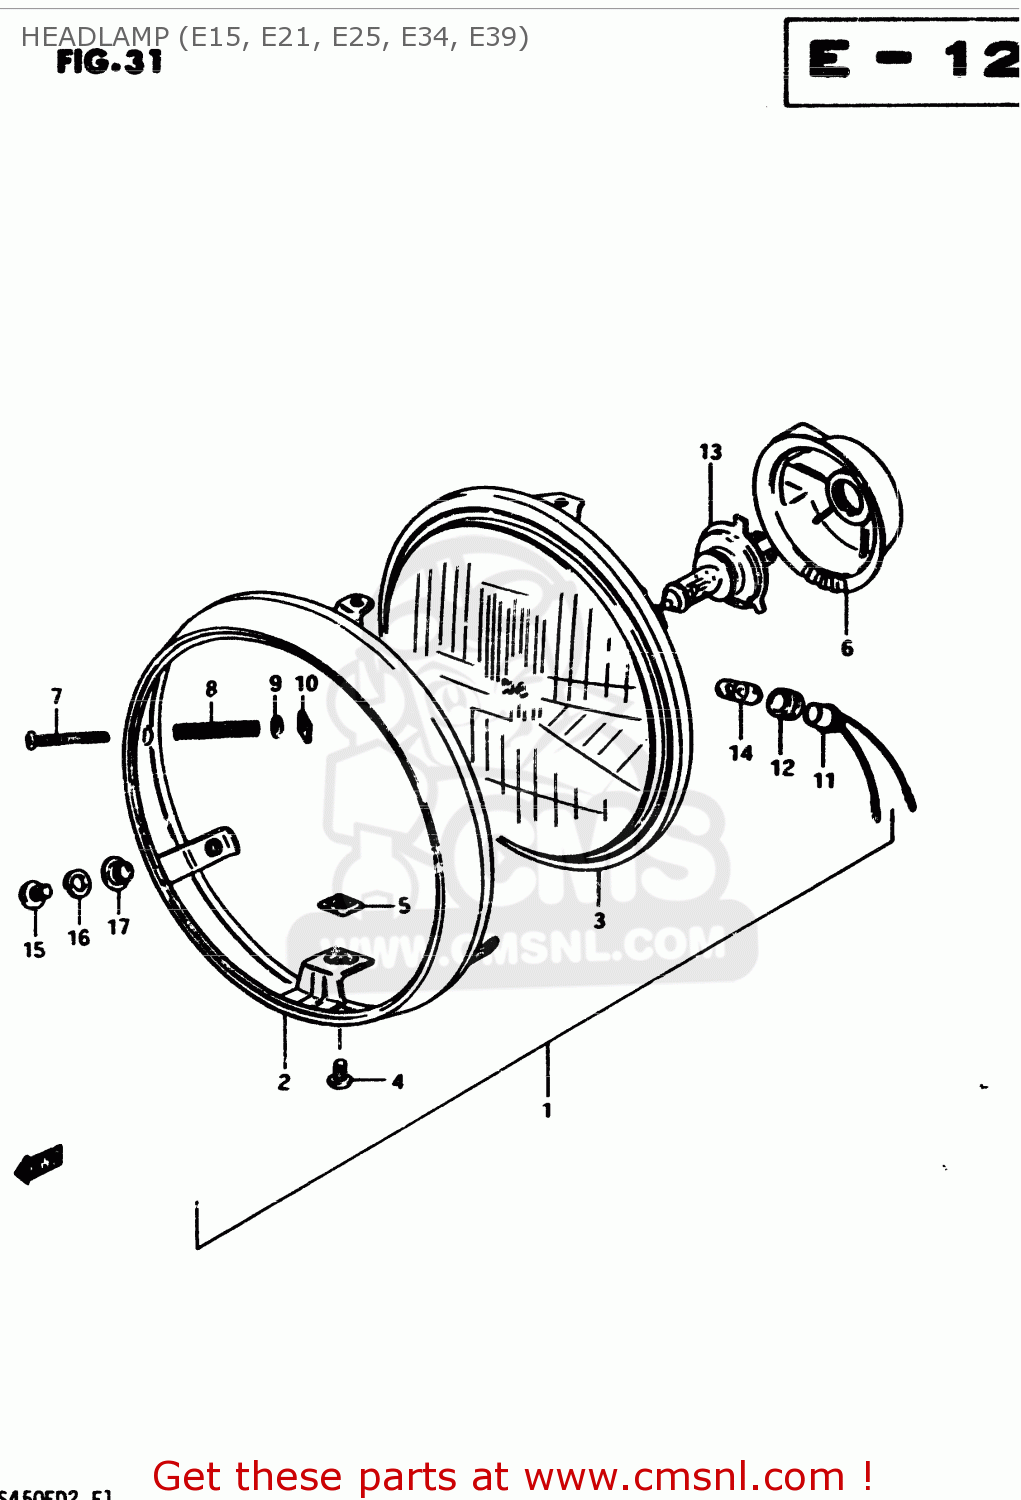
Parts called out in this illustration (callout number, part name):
1	HEADLAMP ASSY
2	RIM
3	LAMP UNIT
4	SCREW
5	NUT,ADJUSTING
6	COVER,SOCKET
7	SCREW
8	SPRING
9	WASHER
10	NUT,HEADLAMP ADJUSTER
11	SOCKET
12	JOINT,RUBBER
13	BULB(12V60/55W,H4)
14	BULB(12V4W)
15	SCREW
16	WASHER,LOCK
17	WASHER
